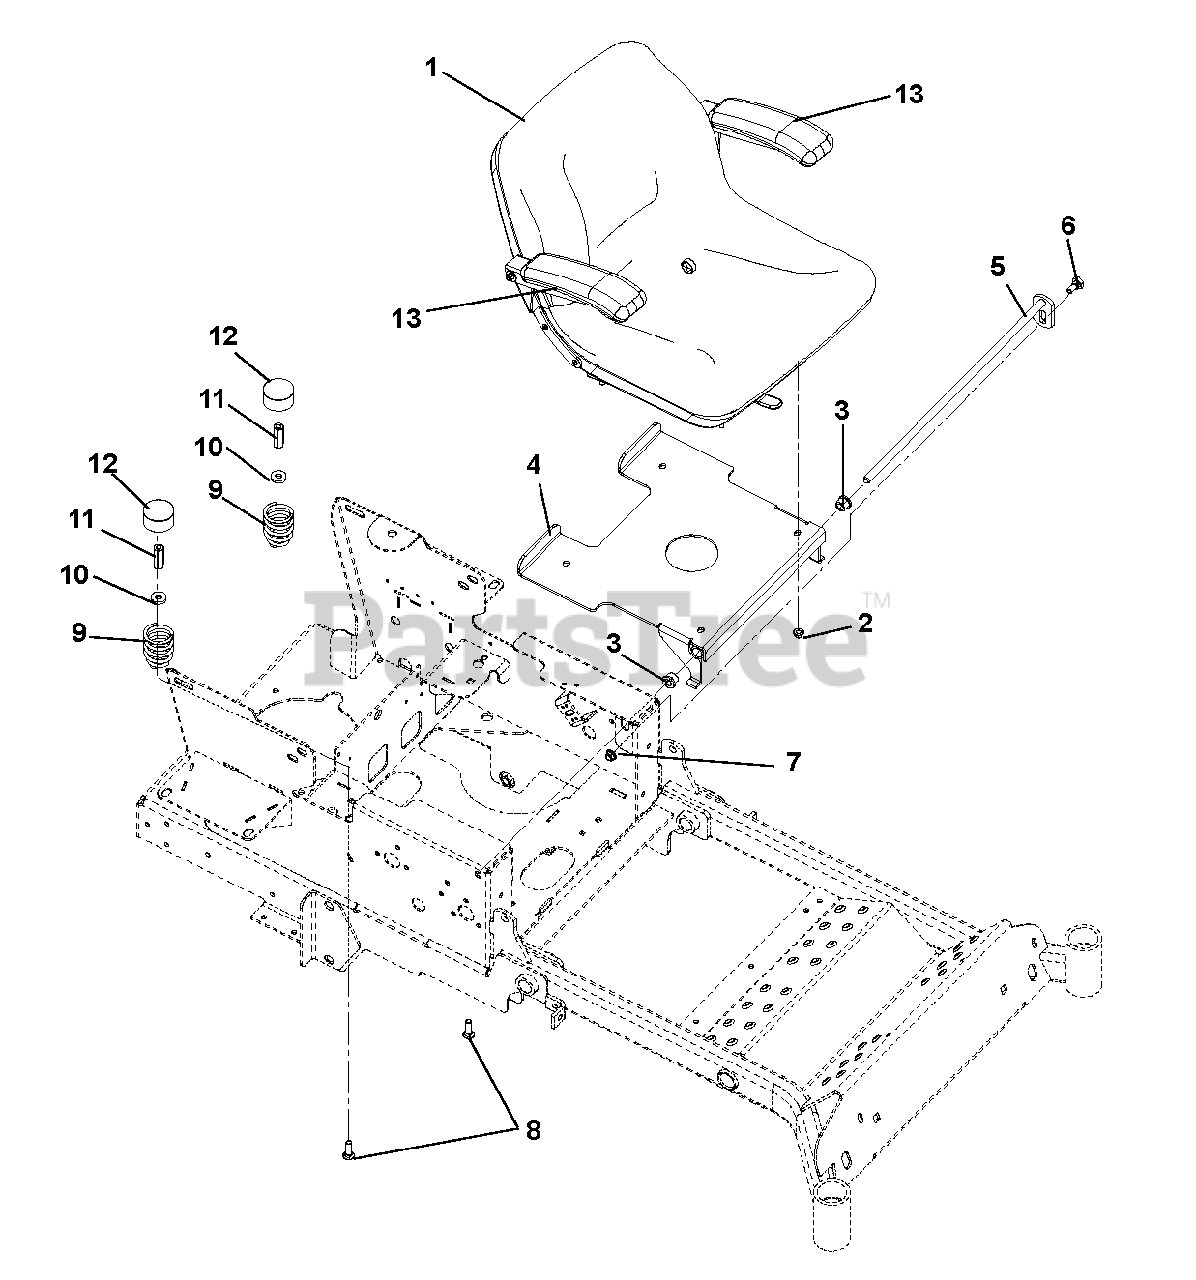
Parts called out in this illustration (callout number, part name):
1	SEAT, MILSCO XB-180
1	SWITCH- SNAP MTG N.O.
2	@NUT-LK-NYL-FLG .31-18 YWZC
3	BSHG, FLG .516X.750X.625X.937
4	WLDMT, SEAT PLATE
5	WMT, SEAT SHAFT
6	BLT,SHLDR EP .38-16X.30 HEX YZ
7	@NUT-SPNLK-FLG .375-16 YWZC
8	@BLT-RDHDSQNK .38-16X1.25 G5YZ
9	SPRING, SEAT
10	WSHR-FL-STL .406X1.00X.188 YWZ
11	NUT COUPLING .375-16X1.75
12	HUB CAP
13	KIT, SEAT ARM RESTS
